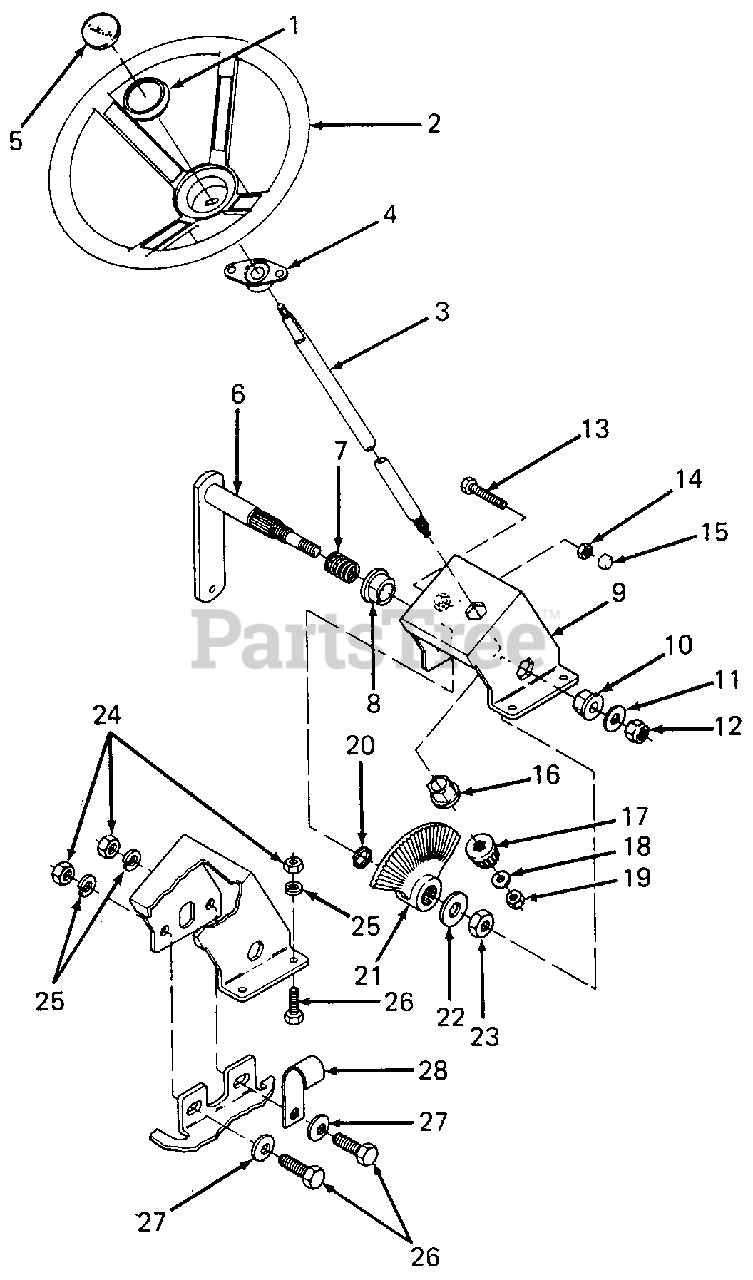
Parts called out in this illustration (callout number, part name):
1	Cap, Steering Wheel
2	Wheel, Steering
3	Shaft, Steering Wheel
4	Bearing, Flange
5	Label, Steering Cap
6	Shaft, Steering
7	Spring, Compression
8	Bearing, Flange
9	Box, Steering
10	Bearing, Flange
11	Washer, Flat, .515 X 1.12 X .100 Thk HDN
12	Nut, Hex Center Lock, 1/2-13 GR5
13	Screw, Hex, 3/8-16 X 2.25 Lg GR5
14	Nut, Hex Jam, 3/8-16 GR5
16	Bearing, Flange
17	Gear, Pinion
18	Washer, Flat, .320 X .60 X .06 Thk HDN
19	Nut, Hex Center Lock, 5/16-24
20	Ring, Snap
21	Gear, Bevel
22	Washer, Flat, .640 X 1.25 X .06 Thk HDN
23	Nut, Hex Jam, 5/8-18
24	Nut, Hex, 5/16-18 GR5
25	Washer, Lock, 5/16
26	Screw, Hex Cap, 5/16-18 X .75 Lg GR5
27	Washer, Bell, .345 X .88 X .060
28	Clip, Cable
